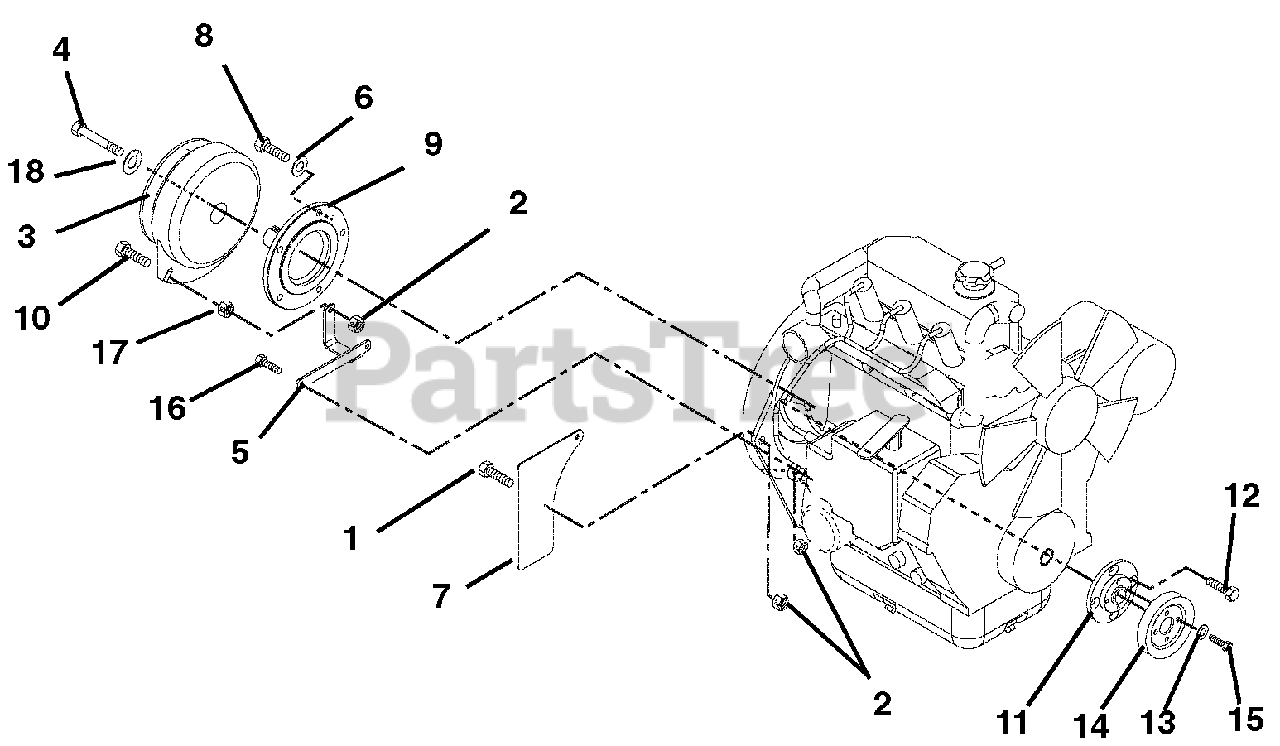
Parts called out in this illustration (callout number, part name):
1	@BLT-HEX .31-18X.75 GR5 YWZC
2	@NUT-LK-TOP-FLG .31-18 YWZC
3	CLUTCH, WARNER 6.323 O/PIN
4	BLT-HEX .44-20X2.50 G5 YZ EP80
5	STABILIZER, CLUTCH
6	@WSHR-LK .31X.078 REG YWZC
7	GUARD, FLYWHEEL
8	BLT, HEX M8-1.25X25 GR8.8YWZC
9	SHAFT, STUB (BRIGGS-DIESEL)
10	@BLT-HEX .31-18X1.50 GR5 YWZC
11	ADAPTER, SHEAVE (DIESEL)
12	BLT, FSCHS M8-1.25X25
13	@WSHR-LK .25X.062 REG YWZC
14	SHEAVE, POLY V 1.000 X 3.25
15	@BLT-HEX .25-20X.75 GR5 YWZC
16	@BLT-HEX .31-18X1.00 GR5 YWZC
17	@NUT-HEX .31-18 YWZC
18	@WSHR-LK .44X.109 REG YWZC
NS	KIT,BRAKE POLE MODULE REPLACE
